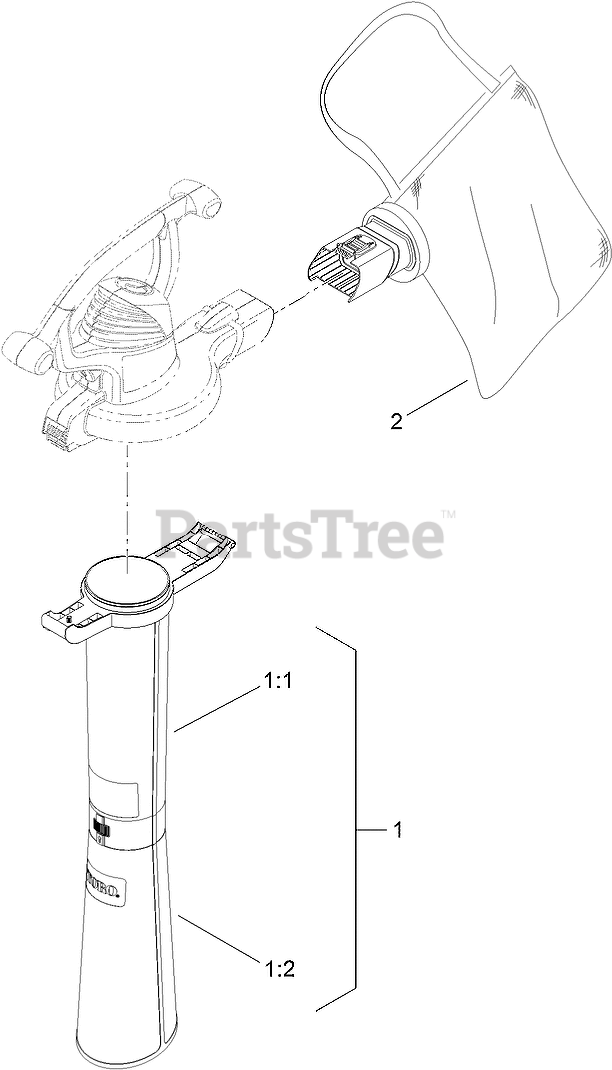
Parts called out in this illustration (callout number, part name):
1	VACUUM TUBE ASM
1:1	TUBE-VACUUM, UPPER
1:2	TUBE-VACUUM, LOWER
2	BAG ASM
